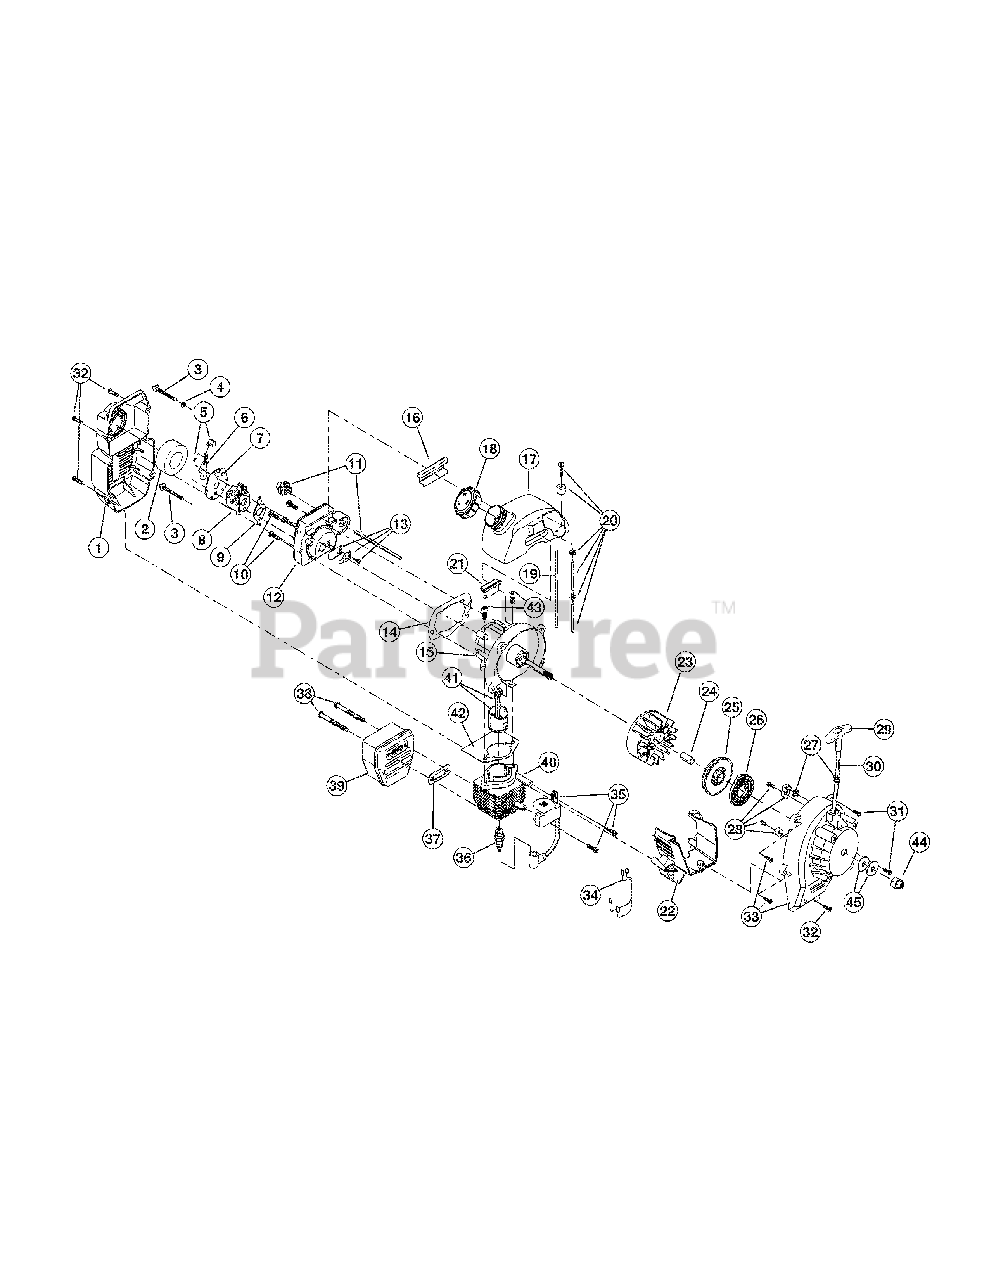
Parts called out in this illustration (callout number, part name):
1	Air Cleaner/Muffler Cover Assembly (includes 2 & 32)
2	Air Cleaner Filter
3	Carburetor Mounting Screw
4	Wavey Washer
5	Choke Knob and Screw
6	Choke Lever Assembly (includes 5)
7	Choke Lever and Plate (includes 6)
8	Carburetor Assembly (includes 9 & 20)
9	Carburetor Gasket
10	Carb Mount Screw
11	Primer and Hose Assembly
12	Carb Mount Assembly (includes 10,13 & 14)
13	Reed Assembly
14	Carburetor Mount Gasket
15	Crank Case Service Assembly (includes 10)
16	Rear Mounting Pad
17	Fuel Tank Assembly (includes 18-20)
18	Fuel Cap Assembly
19	Fuel Return Line
20	Fuel Line Assembly
21	Front Mounting Pad
22	Shroud Extension (includes 32)
23	Flywheel Assembly
24	Spacer
25	Recoil Pulley
26	Recoil Spring
27	Rope Guide
28	Pulley Retainer Assembly
29	Pull Handle
31	Housing Screw
32	Cover Screw
33	Starter Housing Assembly (includes 25-32)
34	Wire Lead Assembly
35	Module Assembly
36	Spark Plug
37	Exhaust Gasket
38	Muffler Mounting Bolt Assembly
39	Muffler Assembly (includes 37 & 38)
40	Cylinder Assembly (includes 42 & 43)
41	Piston and Rod Assembly
42	Cylinder Gasket
43	Cylinder Bolt
44	Impeller Drive Nut
45	Washer
